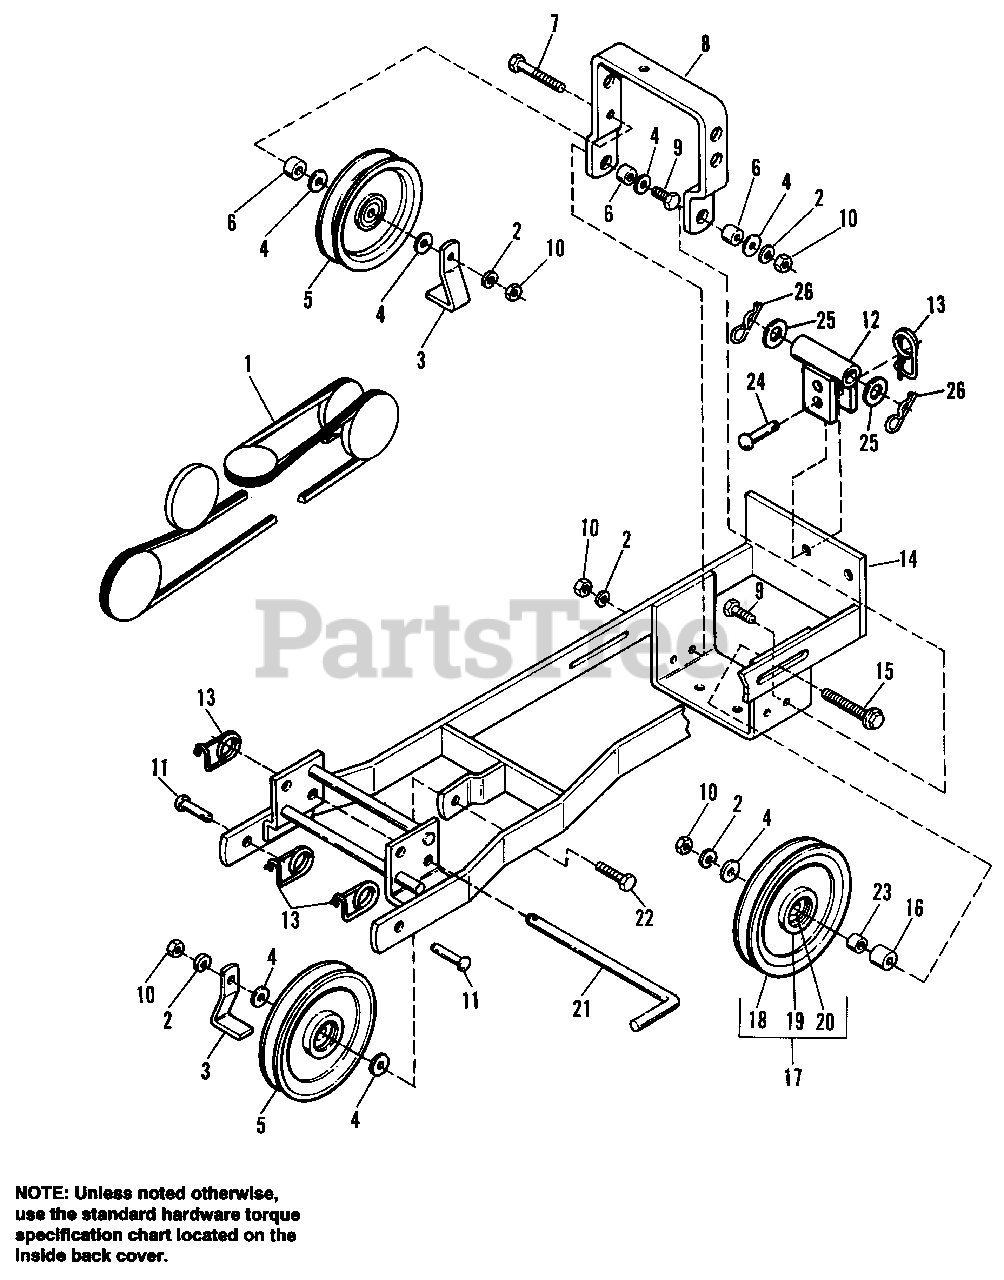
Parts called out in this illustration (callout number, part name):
2	LOCKWASHER, 3/8
3	BELT STOP
4	WASHER, Plain, 5/16
7	CAPSCREW, Hex, 3/8-16 x 2
8	PIVOT, Bracket
9	CAPSCREW, Hex, 3/8-16x 1-1/4
10	NUT, Hex, Full, 3/8-16
11	PIN, Clevis, 3/8
12	SUPPORT ASSY., Rear
13	CLIP, Spring
14	PUSHBAR ASSY.
15	SCREW, Whizlock, 3/8-16 x 2-3/4
17	PULLEY ASSY. w/Bearing (lncl. Ref. Nos. 18, 19, 20)
19	RING, Retaining
22	CAPSCREW, Hex, 3/8-16 x 1-3/4
24	PIN, Clevis
25	WASHER
26	CLIP, Spring
